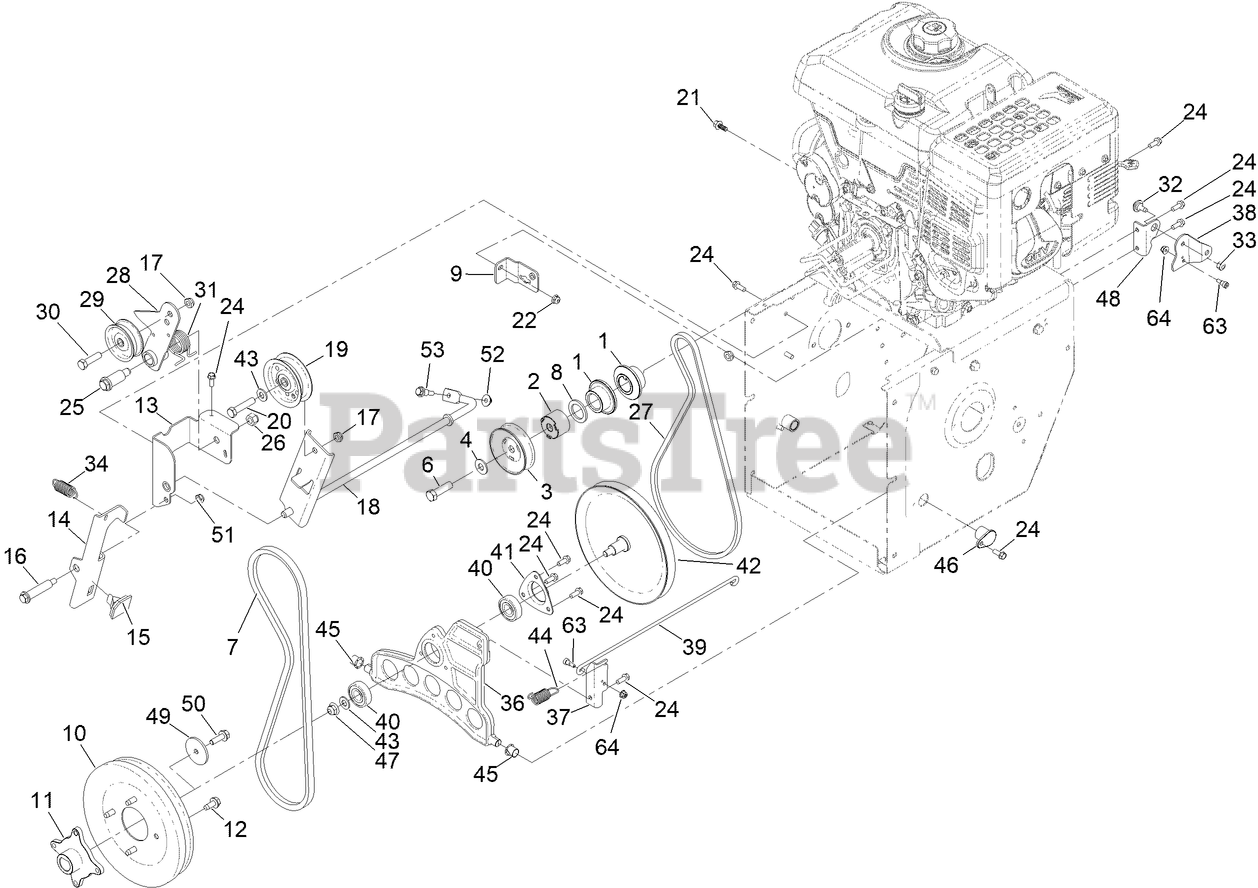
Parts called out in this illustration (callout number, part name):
1	PULLEY-TRACTION, ENGINE
2	PULLEY-SPACER
3	PULLEY-IMPELLER
4	WASHER-PLAIN
6	SCREW-HH
7	BELT-V, HITEMP
8	WASHER-THRUST
9	BRACKET-CLUTCH, IMPELLER
10	PULLEY-IMPELLER
11	HUB-PULLEY
12	SCREW-HWHTF
13	BRACKET-BRAKE, CLUTCH
14	BRAKE ARM
15	PAD-BRAKE
16	BOLT-SHOULDER
17	NUT-HEX
18	IMPELLER CLUTCH ARM ASSEMBLY
19	PULLEY-IDLER
20	SCREW-HH
21	SCREW-HHF
22	NUT-HF
24	SCREW-HWH
25	BOLT-SHOULDER
26	NUT-HEX
27	V-BELT
28	ARM-IDLER, TRACTION
29	PULLEY-IDLER
30	SCREW-HH
31	SPRING-TORSION
32	SCREW-SHOULDER
33	NUT-HEX
34	SPRING-EXTENSION
36	PLATE-FRICTION, WHEEL
37	BKT-TRACTION PLATE
38	BELLCRANK-DRIVE
39	LINK-TRACTION, HD
40	BEARING-BALL
41	RETAINER-BEARING
42	PULLEY-TRACTION
43	WASHER-FLAT
44	SPRING-EXTENSION
45	BUSHING-NYLINER
46	BUSHING-PLATE, TRACTION
47	NUT-HF, NI
49	WASHER-PLAIN
50	SCREW-HHF
51	NUT-HEX
52	NUT-HF
53	BOLT-SHOULDER
63	SCREW-SHOULDER
64	NUT-HF
